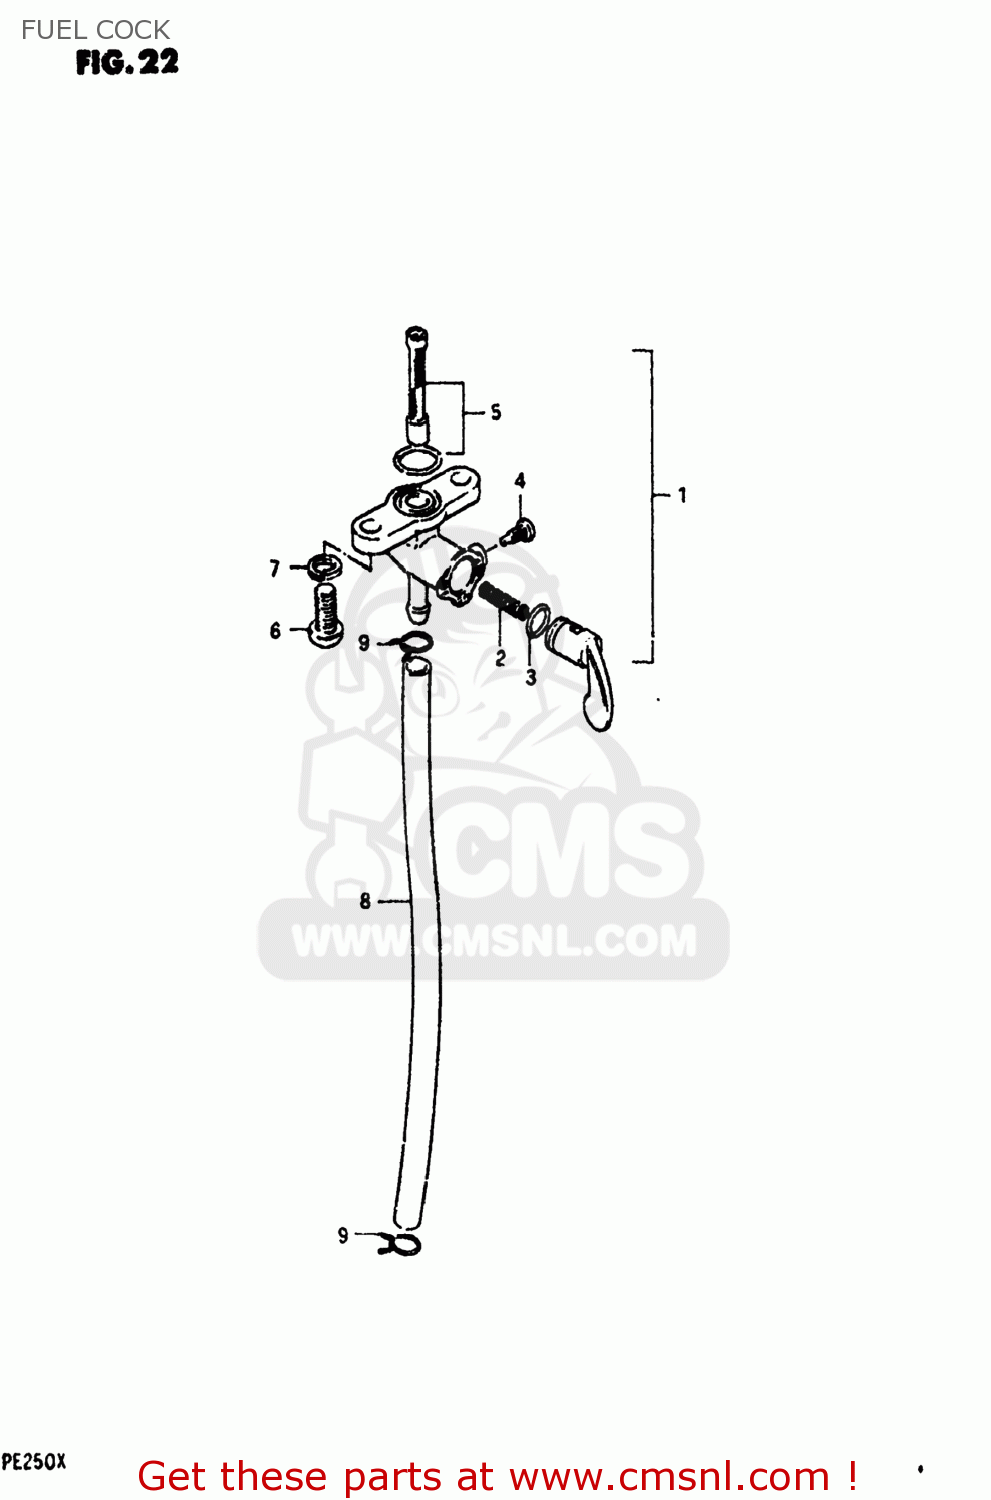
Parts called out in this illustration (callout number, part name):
1	COCK ASSEMBLY,FUEL
2	SPRING,FUEL COCK VALUE
3	O RING,LEVER
4	SCREW
5	FILTER SET FUEL
6	SCREW
7	LOCK WASHER
8	HOSE
9	CLAMP
